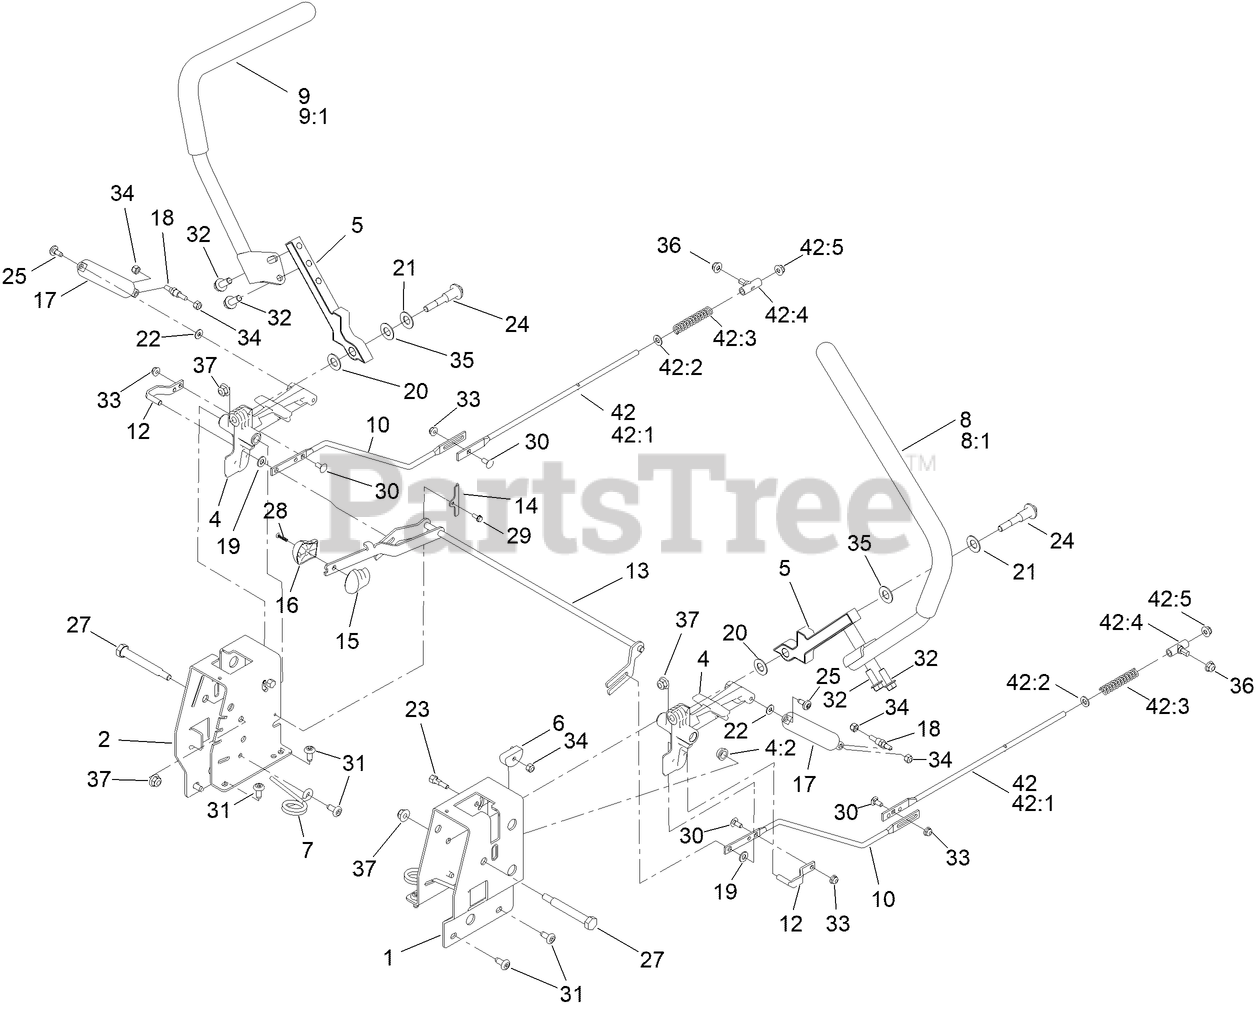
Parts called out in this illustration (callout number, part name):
1	PLATE-CONTROL BOX, LH
2	PLATE-CONTROL BOX, RH
4	ACTUATOR ARM ASM
4:2	BUSHING-FLANGE
5	ARM-CONTROL
6	ECCENTRIC
7	SPRING-TORSION
8	HANDLE-CONTROL, LH
9	HANDLE-CONTROL, RH
10	ROD-HYDRO, FRONT
12	PIN-ROD, HYDRO
13	SPEED CONTROL ASM
14	PLATE-RETAINER
15	KNOB-RH
16	KNOB-LH
17	DAMPER-NON CAVITATING
18	STUD-DAMPER
19	SPACER-NYLON
20	WASHER-NYLON
21	WASHER-BELLEVILLE
22	WASHER
23	BOLT-PIVOT, ECCENTRIC
24	BOLT-PIVOT
25	SCREW-SHOULDER
27	BOLT-PIVOT
28	SCREW-PPH
29	SCREW-TAPTITE
30	BOLT-CARR
32	SCREW-HHF
33	NUT-HF
34	NUT-HEX
35	WASHER
36	NUT-HF
37	NUT-HF, NI
42	ROD HYDRO ASM
42:1	ROD-HYDRO, REAR
42:2	WASHER-PLAIN
42:3	SPRING-COMPRESSION
42:4	MOUNT-ROD, HYDRO
42:5	NUT-HF
